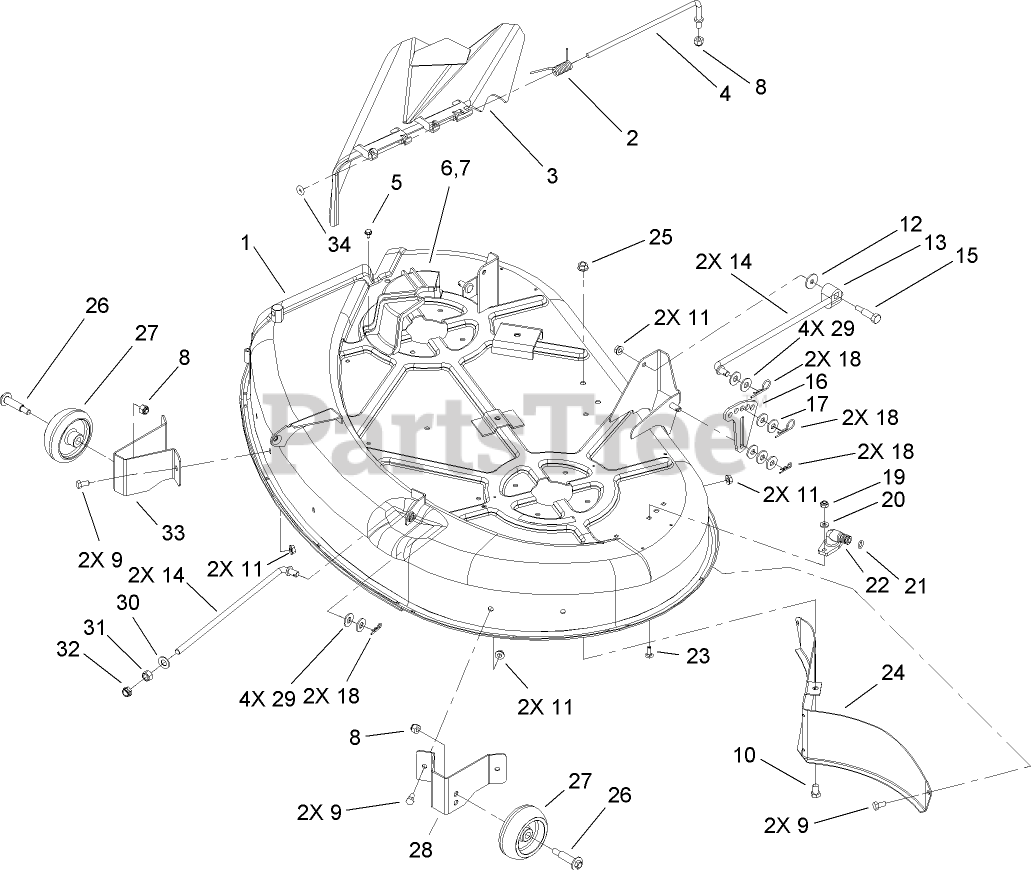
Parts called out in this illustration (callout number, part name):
2	SPRING
3	DEFLECTOR ASM
4	ROD-PIVOT
5	SCREW-HWHTF
6	GUIDE-BELT, LH
7	GUIDE-BELT, RH
8	NUT-LOCK, NI
9	SCREW-HH
10	SCREW-HH
11	NUT-HF
12	WASHER-PIVOT
13	TRUNNION-HOC
14	ROD-HANGER
15	SCREW-SHOULDER, HH
16	LINK-ADJUSTING, HOC
17	WASHER-HARDENED
18	PIN-HAIR
19	NUT-LOCK, NI
20	WASHER-FLAT
21	O-RING
23	BOLT-CARR
24	BAFFLE-REAR
25	NUT-HF
26	SCREW-SHOULDER, HWH
27	WHEEL-GAGE
28	BRACKET-GAGE WHEEL, FRONT (LH)
29	WASHER-FLAT
30	WASHER-FLAT
31	NUT-HEX
32	NUT-LOCK, NI
33	BRACKET-GAGE WHEEL, FRONT (RH)
34	O-RING
